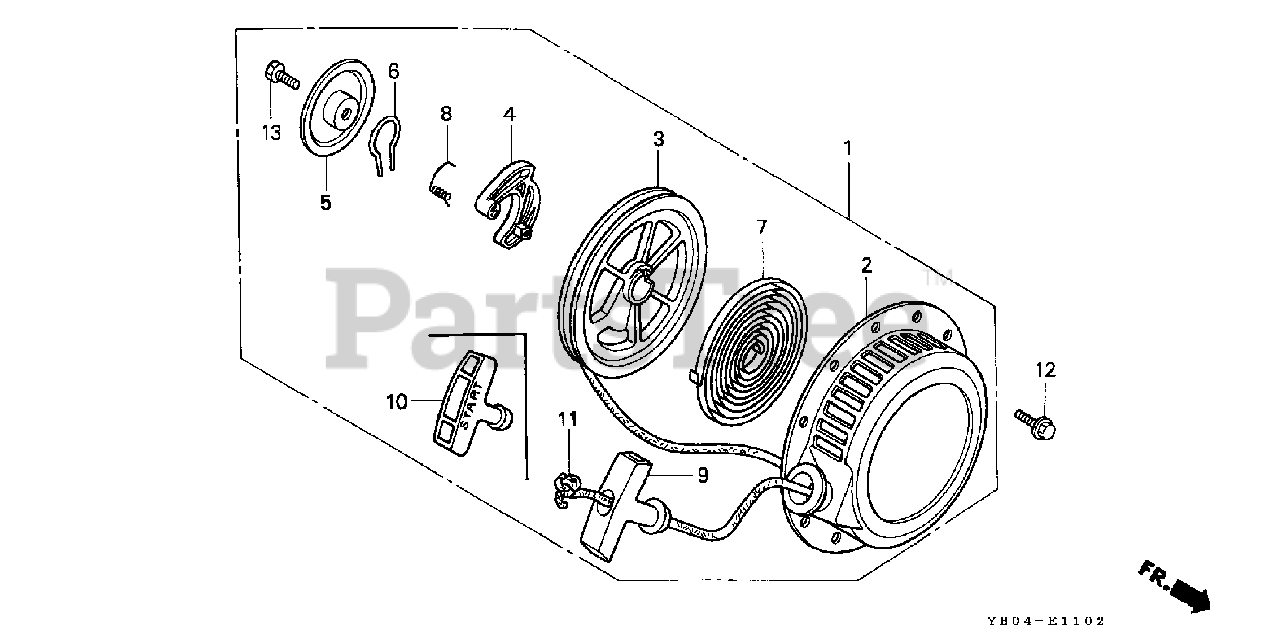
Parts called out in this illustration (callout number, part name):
1	STARTER ASSY., RECOIL *R8* (BRIGHT RED)
1	STARTER ASSY., RECOIL *R280* (POWER RED)
2	CASE, RECOIL STARTER *R8* (BRIGHT RED)
3	REEL, RECOIL STARTER
4	RATCHET, STARTER
5	PLATE, FRICTION
6	SPRING, FRICTION
7	SPRING, RECOIL STARTER
8	SPRING, RETURN
9	KNOB, STARTER
10	KNOB, RECOIL STARTER
11	ROPE, RECOIL STARTER (#4X65") (N/A: USE P/N 08540-ZG921-11)
12	BOLT, FLANGE (6X8)
13	BOLT, HEX. (6X20)
